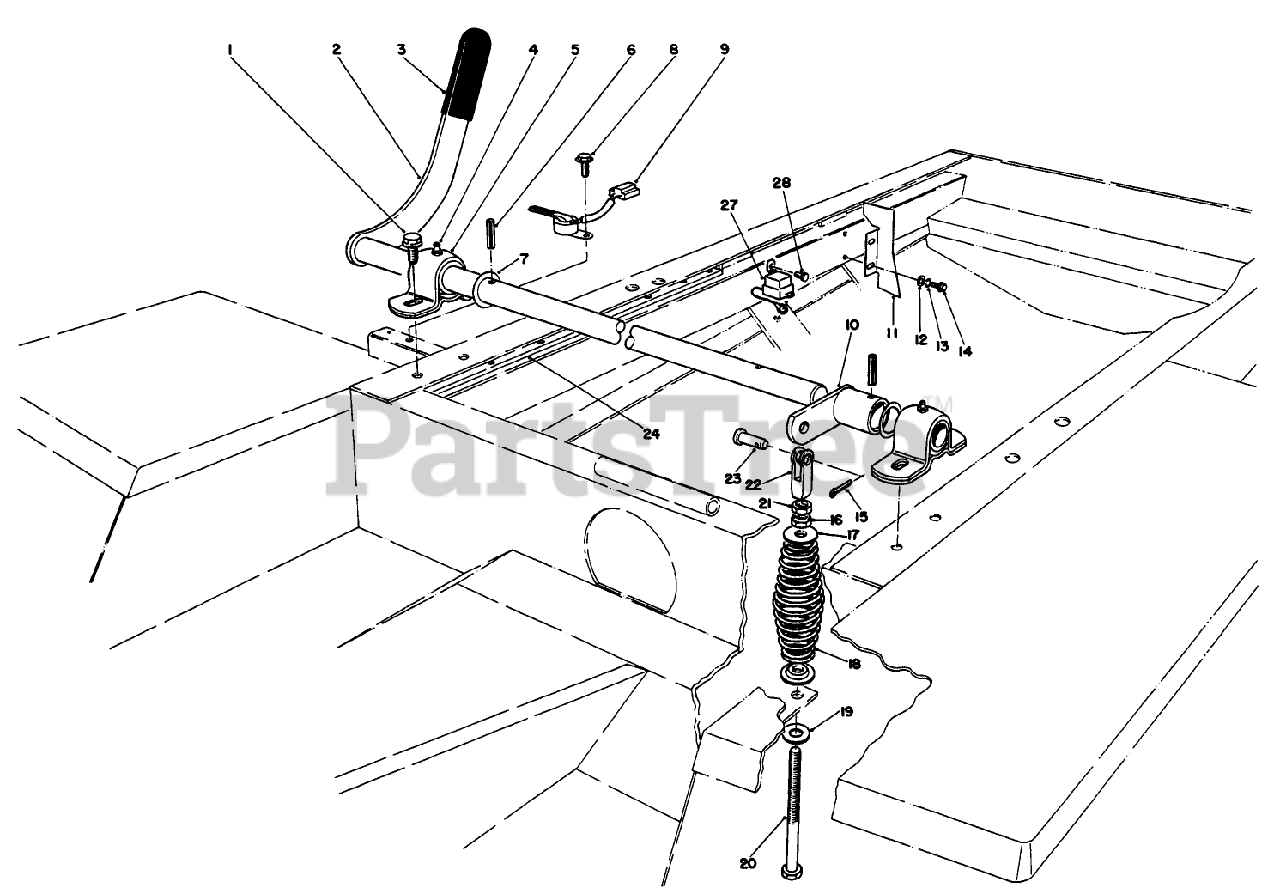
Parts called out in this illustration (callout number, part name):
1	SCREW-HHF
2	P.T.0. Lever
3	GRIP-HANDLE
4	FITTING-GREASE
5	BEARING
6	PIN-SPRING
7	THRUST WASHER
8	SCREW-THD FRM,HWH
9	SWITCH ARM
10	Arm-Engagement
11	Shield-Heat
12	WASHER-PLAIN
13	WASHER-LOCK
14	SCREW-HWHTF
15	PIN-COTTER
16	NUT-HEX
17	SPRING RET TOP
18	COMP SPRING
19	WASHER
20	SCREW-ADJUSTING
21	NUT-HJ
22	PLUG-PIPE, SQH
23	PIN-CLEVIS
24	Bar Frame Rail
27	RELAY
28	SCREW-HWH
